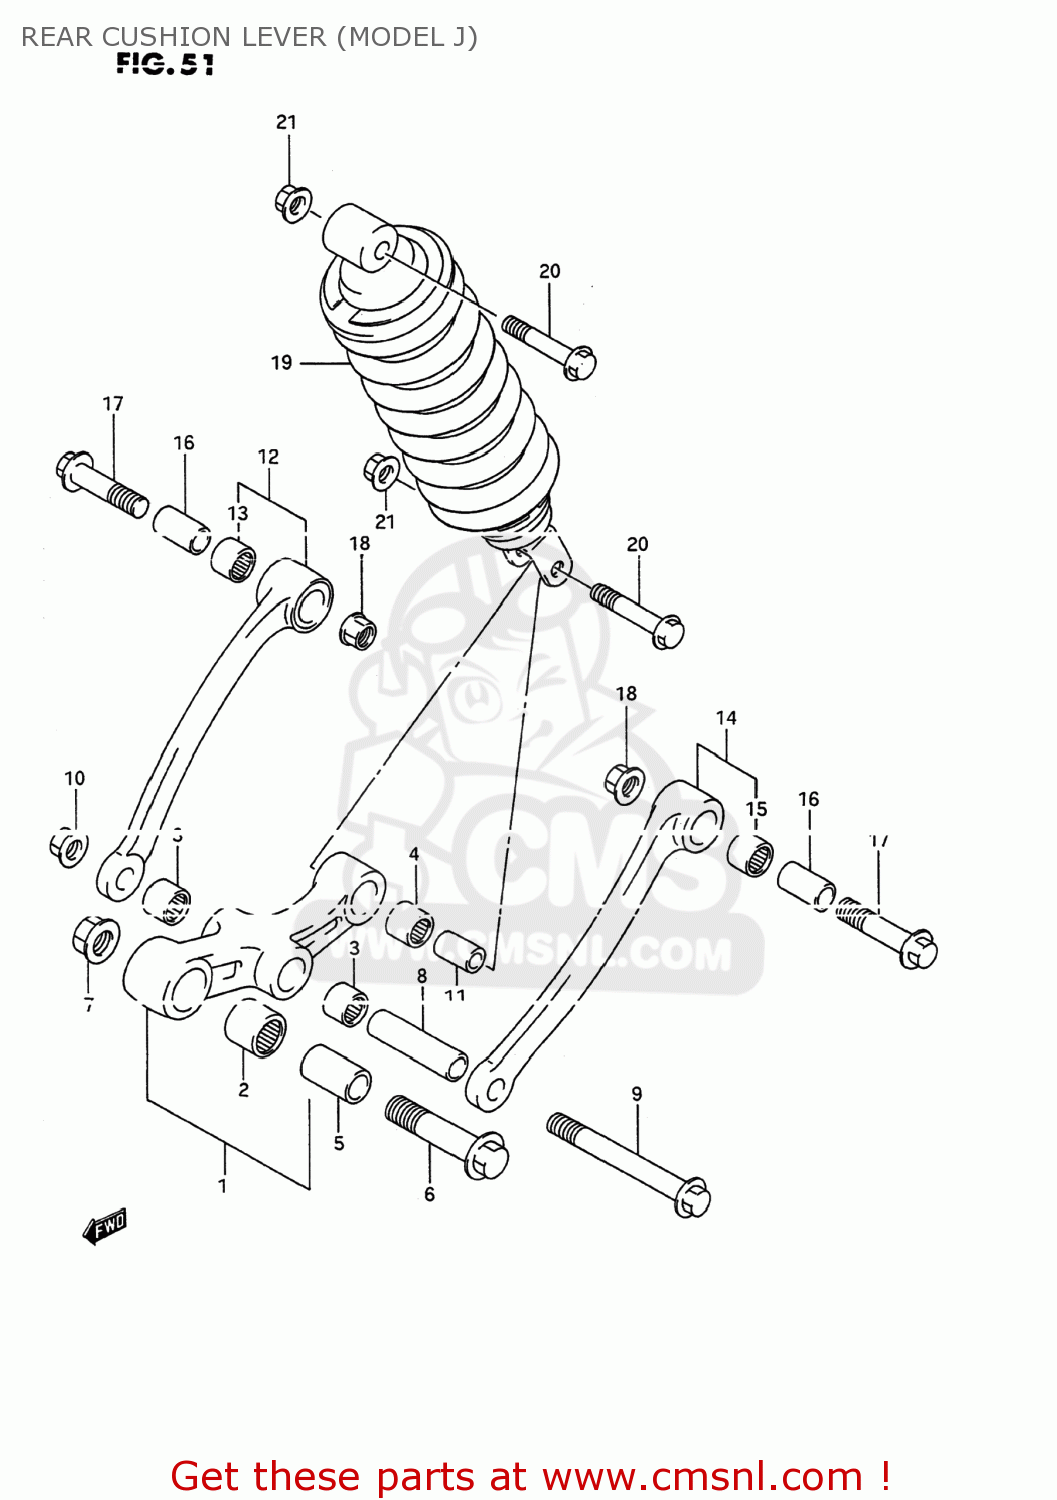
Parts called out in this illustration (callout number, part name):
1	LEVER SET,RR CUSHION
2	BEARING(20X27X30)
3	BEARING(17X24X25)
4	BEARING(17X24X26)
5	SPACER(14X20X34)
6	BOLT(14X62)
7	NUT 14MM
8	SPACER(12X17X60)
9	BOLT(12X96)
10	NUT 12MM
11	SPACER,RR CUSHION LEVER
12	ROD SET,RR CUSHION,R
13	BEARING(17X24X26)
14	ROD SET,RR CUSHION,L
15	BEARING(17X24X26)
16	SPACER(12X17X29)
17	BOLT L:52
18	NUT 12MM
19	ABSORBER ASSEMBLY,REAR SHOCK
20	BOLT(10X52)
21	NUT 10MM
